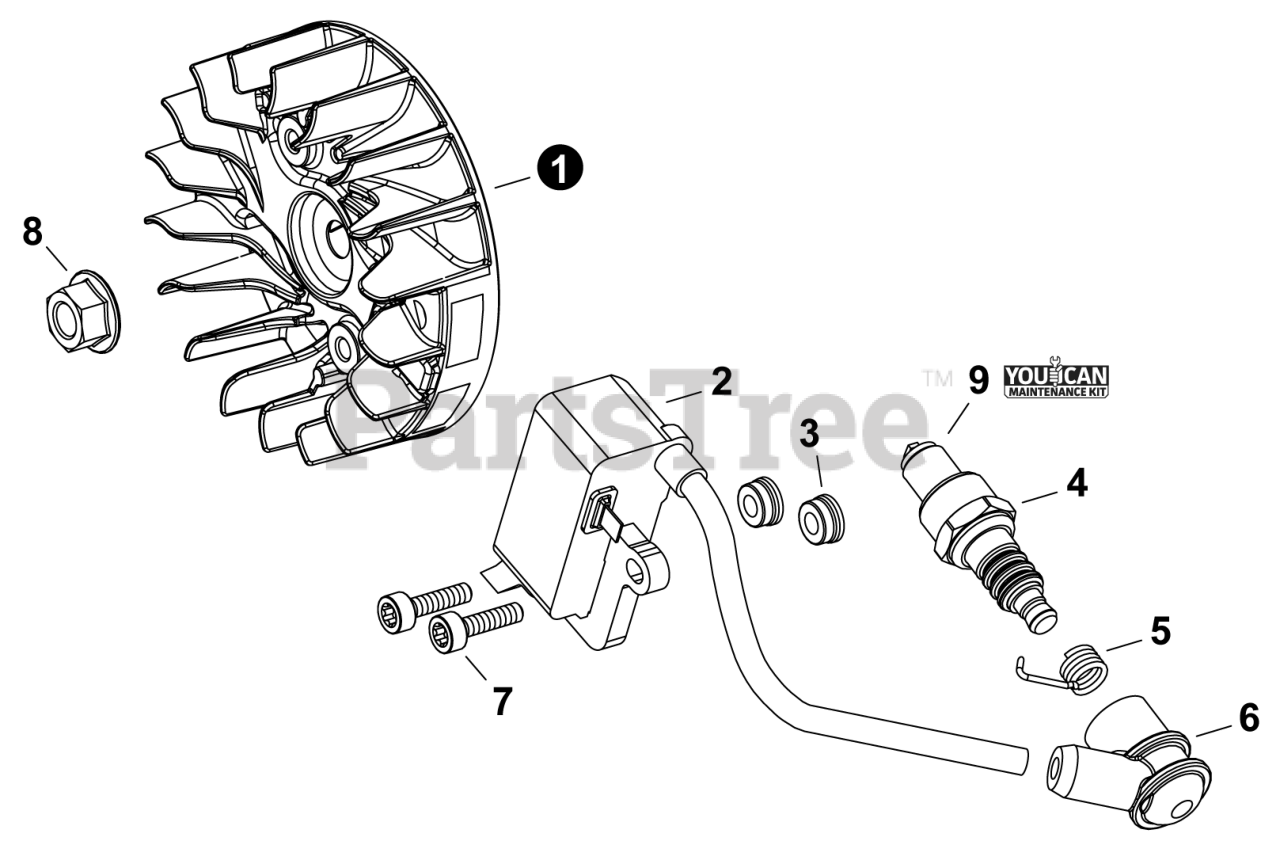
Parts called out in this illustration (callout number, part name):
1	FLYWHEEL
2	COIL, IGNITION
3	COLLAR 4
4	SPARK PLUG - CMR7H
5	TERMINAL, SPARK PLUG
6	CAP, SPARK PLUG
7	BOLT, TORX 4x16
9	TUNE-UP KIT - YOUCANT
